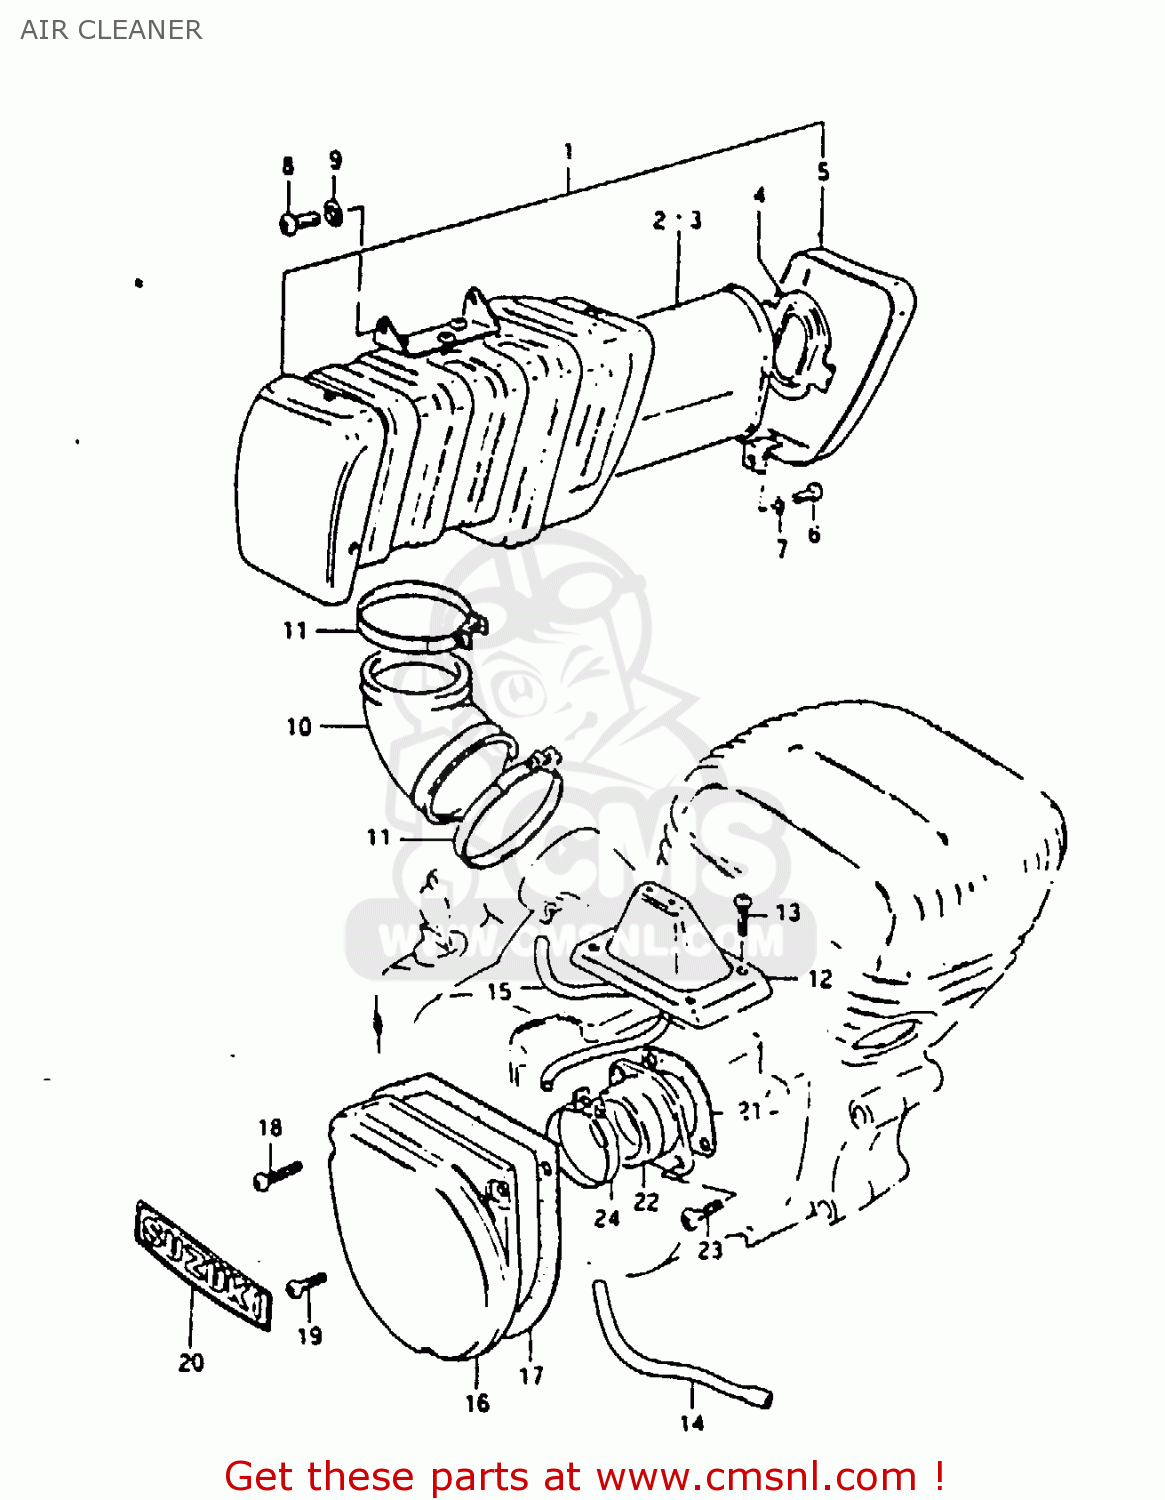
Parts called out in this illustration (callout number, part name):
1	CLEANER ASSY, AIR
2	FILTER ASSY,AIR CLEANER
3	FILTER
4	HOLDER
5	COVER
6	BOLT 5X10
7	LOCK WASHER
8	SCREW 6X12
9	WASHER
10	HOSE,CARBURETOR AIR INLET
11	CLAMP
12	CAP,CARBURETOR TOP
13	SCREW
14	HOSE,CARBURETOR AIR VENT
15	HOSE (3X5X300)
16	CAP, CARB. INSPECTION
17	GASKET,CARB INSPECTION CAP (NAS)
18	SCREW 5X20
19	SCREW
20	EMBLEM,CARB INSPECTION CAP
21	GASKET,CARBURETOR (NAS)
22	PIPE,INTAKE
23	SCREW
24	CLAMP
